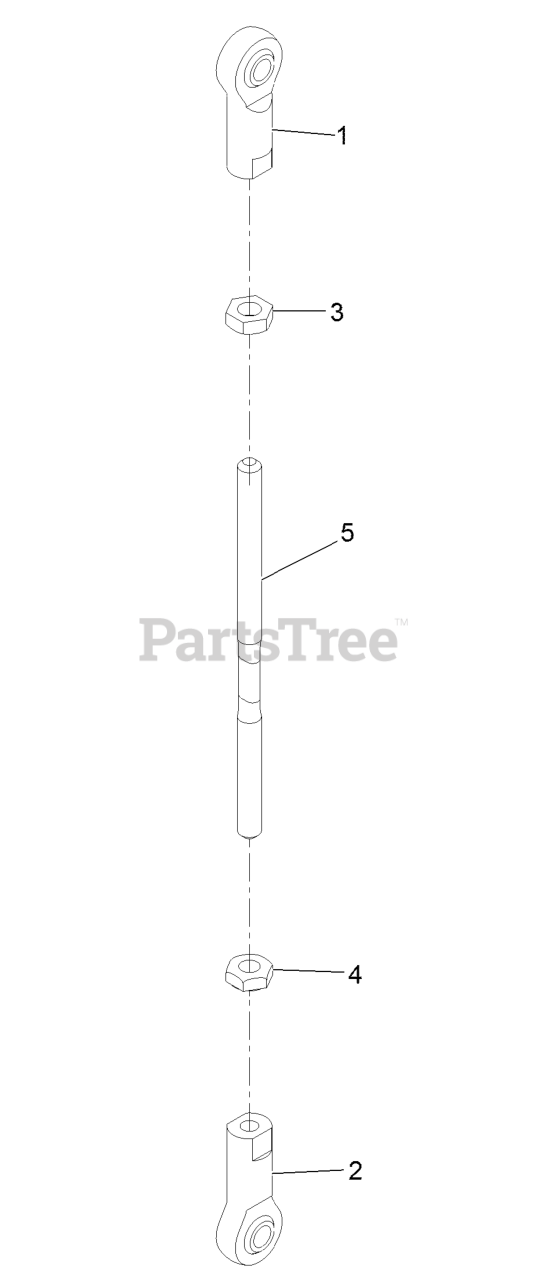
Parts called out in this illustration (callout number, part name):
1	ROD END-BALL JOINT
2	JOINT-BALL, LH
3	NUT-JAM
4	NUT-JAM
